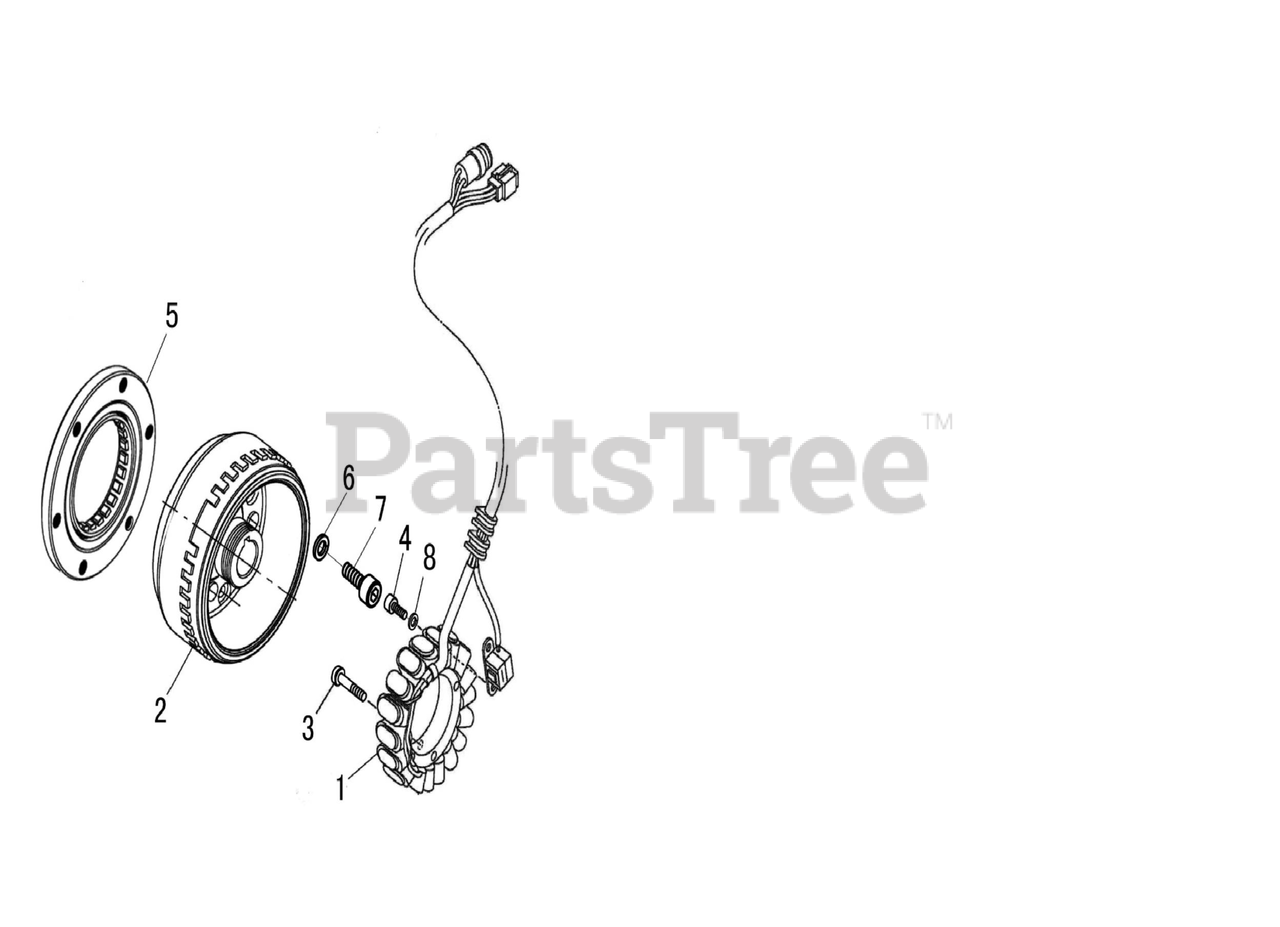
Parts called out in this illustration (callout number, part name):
1	GENERATOR STATOR ASSEMBLY
2	GENERATOR ROTOR ASSEMBLY
3	Hex head bolt & plain washer assemblies M6X30
4	Hex head cap screw M5X12
5	Overrunning Clutch
6	Spring Washer-8
7	Hex head cap screw M8X16
8	SPRING WASHER
